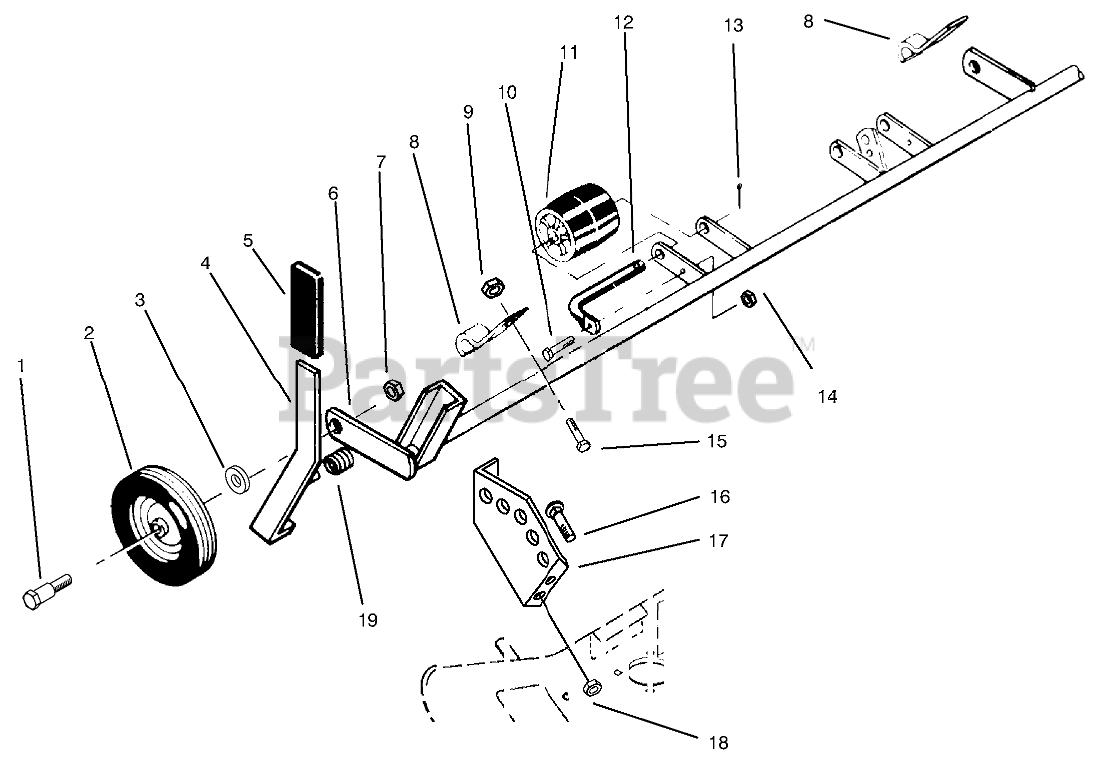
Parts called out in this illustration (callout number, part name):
1	BOLT-SHOULDER
2	WHEEL ASM
3	Spacer
4	Lever
6	Support-Gage Wheel
7	NUT-HEX
8	Clamp
9	NUT-LOCK, NI
10	SCREW-HH
11	Roller
12	ROLLER-SHAFT
13	PIN-COTTER
14	NUT-LOCK, NI
15	BOLT-CARR
16	BOLT-CARR
17	Quadrant
18	NUT-LOCK, NI
19	SPRING-COMPRESSION
